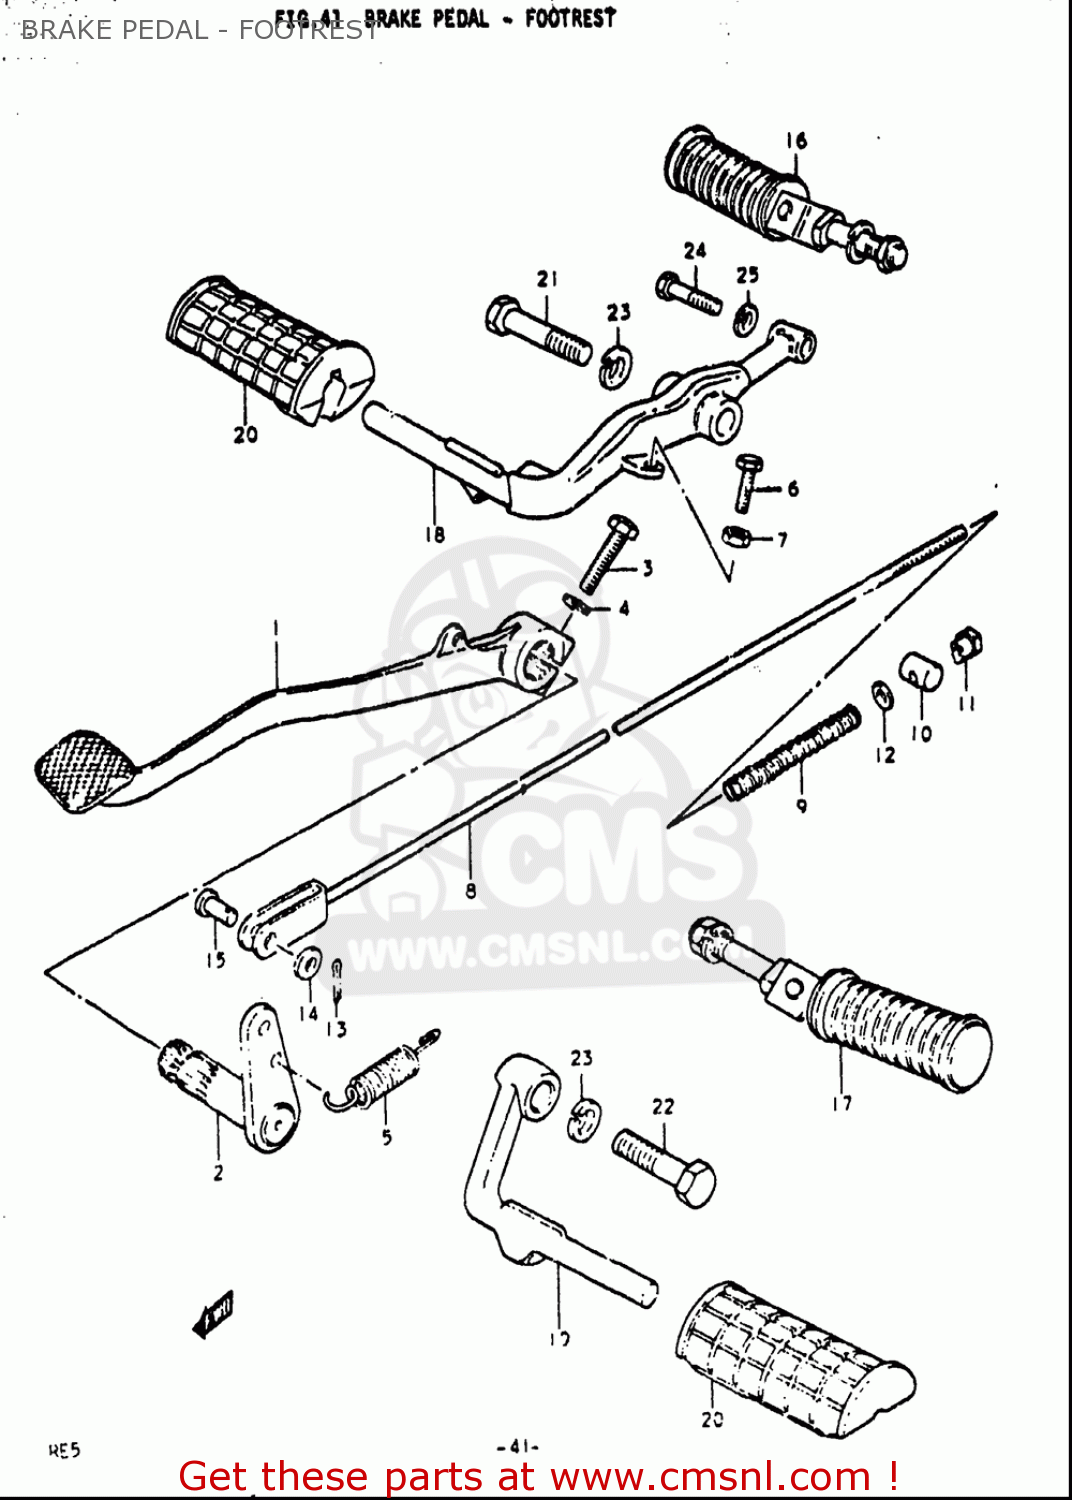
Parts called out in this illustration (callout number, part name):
3	BOLT
4	WASHER,LOCK
6	BOLT(6X23)
7	NUT
9	SPRING
10	PIN(13X18)
11	NUT
12	WASHER
13	PIN
14	WASHER
15	PIN(L:13.5)
20	RUBBER,FR FOOTREST
22	BOLT
23	WASHER,LOCK
24	BOLT
25	WASHER,LOCK
